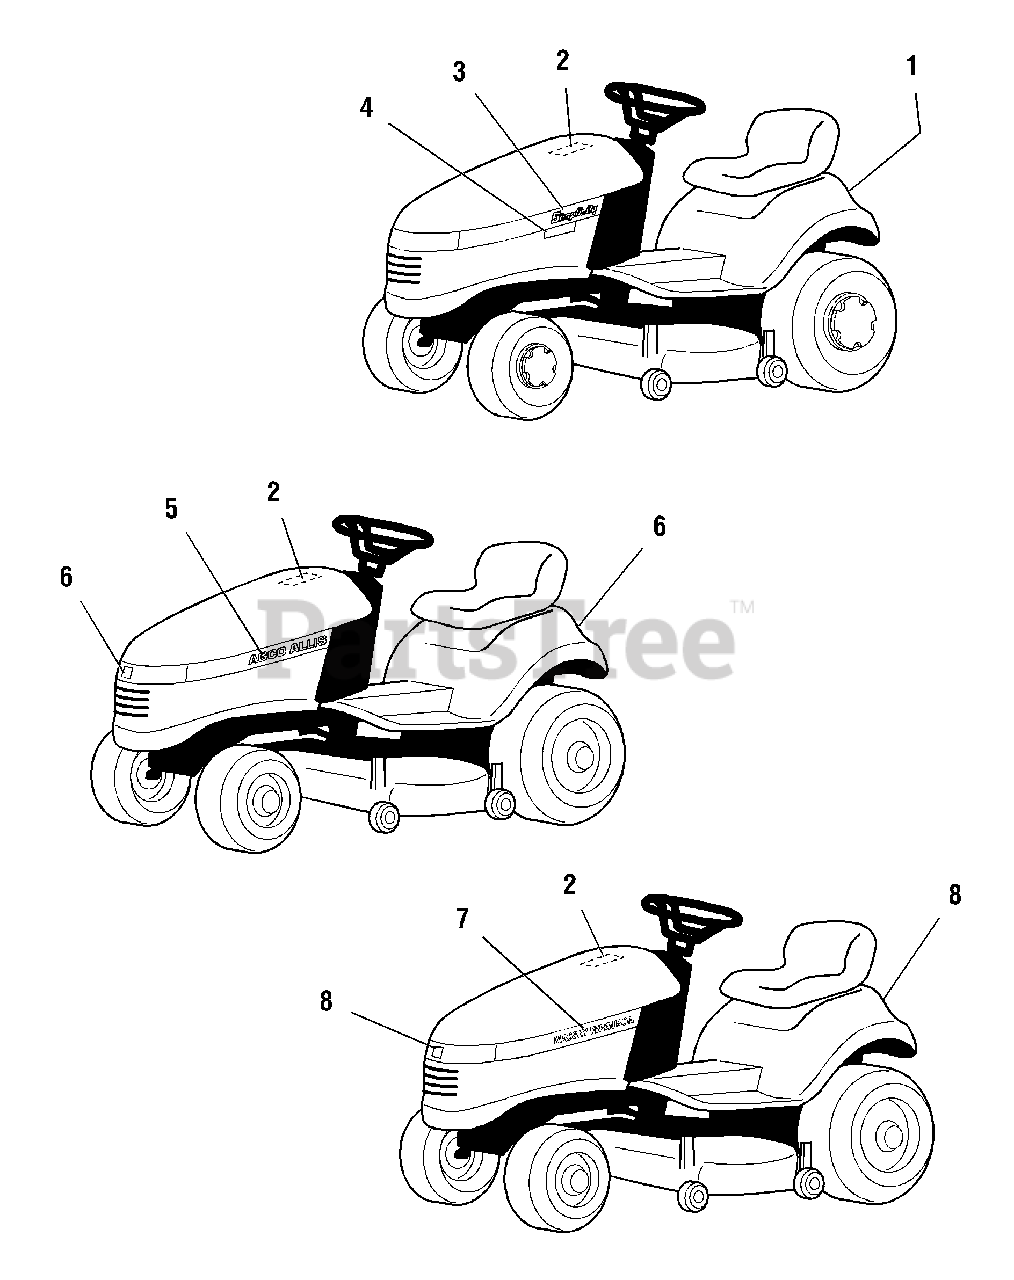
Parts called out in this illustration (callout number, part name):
1	DECAL, Simplicity
2	DECAL, Touch-Up Paint
3	DECAL, Hood, Simplicity, LH
3	DECAL, Hood, Simplicity, RH
4	DECAL, Hood, Hydro 14
4	DECAL, Hood, 5-Speed 14
4	DECAL, Hood, Hydro 16
4	DECAL, Hood, 5-Speed 16
5	DECAL, Hood, 514H, LH
5	DECAL, Hood, 514H, RH
5	DECAL, Hood, 514G, LH
5	DECAL, Hood, 514G, RH
5	DECAL, Hood, 516H, LH
5	DECAL, Hood, 516H, RH
5	DECAL, Hood, 516G, LH
5	DECAL, Hood, 516G, RH
6	DECAL, AGCO Allis
7	DECAL, Hood, 2514H, LH
7	DECAL, Hood, 2514H, RH
7	DECAL, Hood, 2514G, LH
7	DECAL, Hood, 2514G, RH
7	DECAL, Hood, 2516H, LH
7	DECAL, Hood, 2516H, RH
8	DECAL, Massey Ferguson
